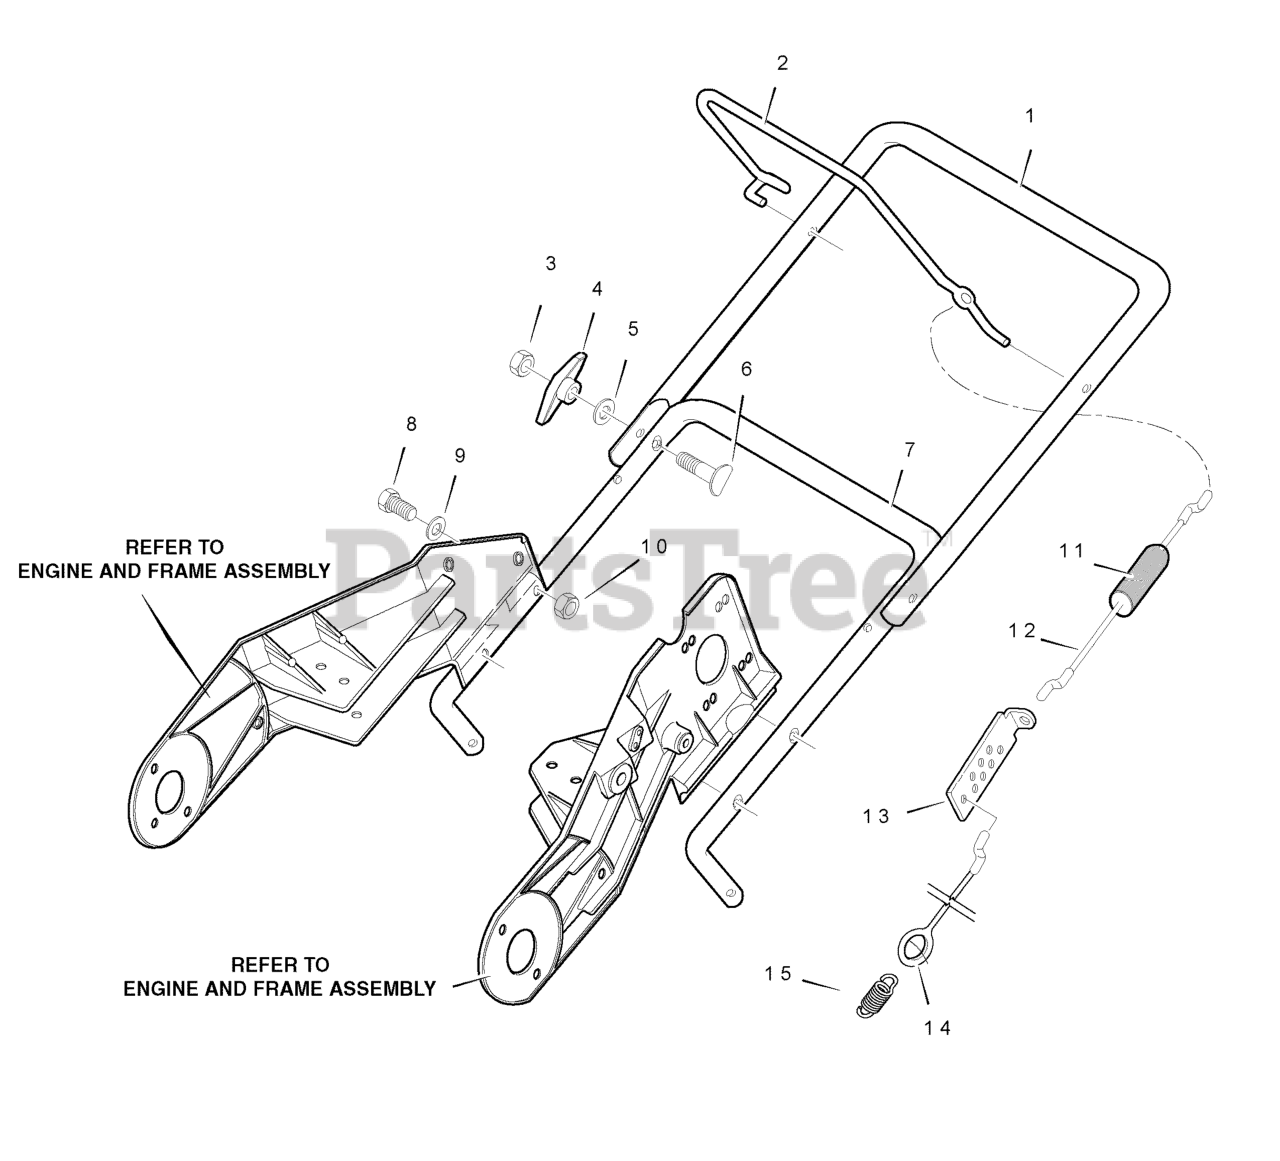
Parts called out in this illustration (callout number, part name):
1	HANDLE, UPPER
2	BAIL, CONTROL
3	NUT, 5/16-18 HEX
4	KNOB, WING
5	WASHER, FORM
6	BOLT, 5/16-18 X 2.00
7	HANDLE, LOWER
8	SCREW, 1/4-20 X 1.25
9	WASHER, FLAT
10	NUT, 1/4-20 HEX
11	BOOT, CLUTCH SPRING
12	CABLE, UPPER CONTROL
13	BRACKET, CABLE ADJUST
14	CABLE, LOWER CONTROL
15	SPRING, EXTENSION
